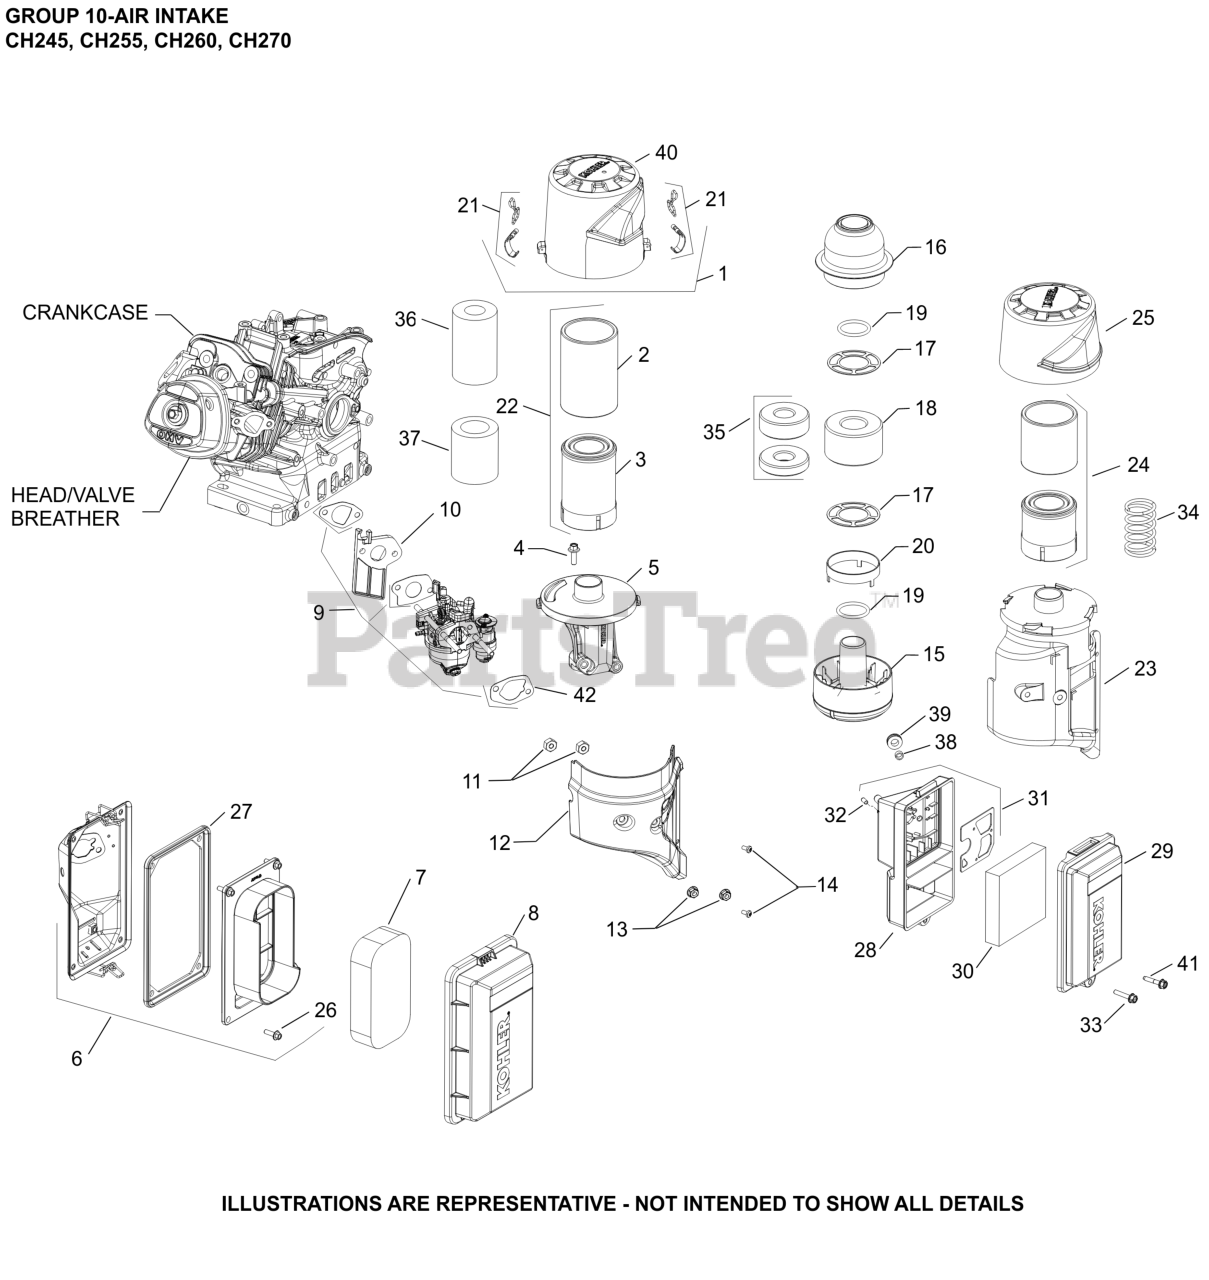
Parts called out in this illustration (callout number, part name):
13	NUT, HEX FLANGE LOCK (M6)
23	BASE, AIR CLEANER ASSEMBLY
24	ELEMENT, FILTER ASSEMBLY
25	COVER, AIR CLEANER ASSEMBLY
